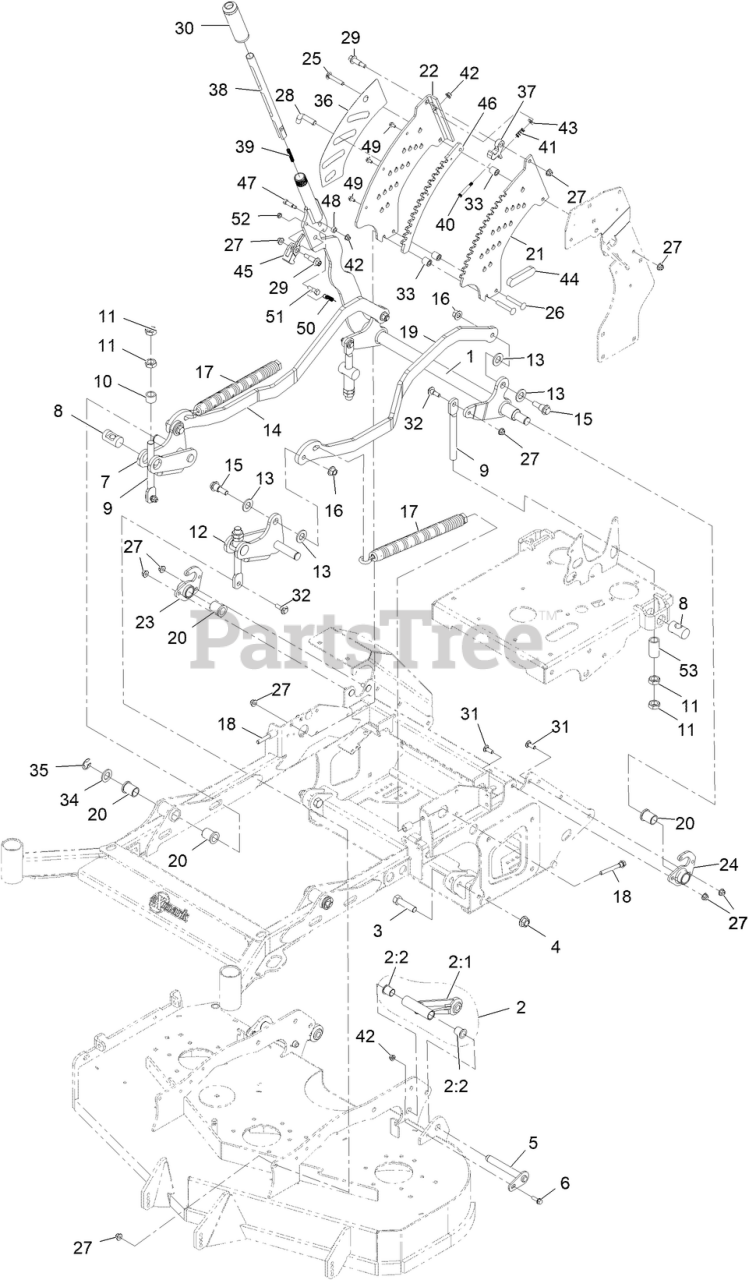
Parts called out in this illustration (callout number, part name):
1	CROSS SHAFT-DECKLIFT-REAR [BLACK]
2	ASM-DECK STRUT W/BUSHINGS
2:1	ASM-Deck Strut
2:2	BUSHING-IGUS FLNG .75X1
3	SCREW-HH
4	NUT-FLNG 5/8-18 CTRLOCK GR G
5	ASM-DECK STRUT PIN
6	SCREW-HHF
7	Weld-Arm-Decklift-Front-RH
8	TRUNION-DECK LIFT
9	Link,Deck Lift Adjuster
10	SPACER-DECKLIFT
11	NUT-JAM
12	Weld-Arm-Decklift-Front-LH
13	WASHER-FLAT
14	LINK-DECKLIFT-RH
15	SCREW-SHOULDER, HHF 1/2-13 X 1.12
16	Nut-Lock 1/2-13
17	SPRING-EXTENSION
18	BOLT-SHOULDER
19	LINK-DECKLIFT-LH
20	BUSHING-FLANGED
21	Plate-Inner-HOC
22	Plate-Outer-HOC
23	SUPPORT-HOC SHAFT RH
24	SUPPORT-HOC SHAFT LH
25	BOLT-CARR, SHORT NECK
26	SCREW-CARR
27	NUT-HF, NI
28	PIN-HOC
29	BOLT-SHOULDER
30	GRIP-HANDLE-DECKLIFT
31	SCREW-CARR
32	SCREW-SHOULDER, HHF
33	SPACER-HOC
35	RING-RETAINING, EXT
36	DECAL-HEIGHT OF CUT
37	PAWL-DECKLIFT
38	PLUNGER-TOP
39	SPRING-COMPRESSION
40	SCREW-SHOULDER-CAP
41	SPRING-COMPRESSION
42	NUT-HF, NI
44	PLATE-GUIDE HOC INNER
45	Pawl-Lock-Decklift
46	Plate-Doubler-HOC-Lock
47	BOLT-SHOULDER
49	SCREW-HWH
50	SPRING-EXTENSION
51	BOLT-SHOULDER
52	NUT-LOCK, NI
53	SPACER 1.13 O.D. X .81 I.D. X 2.05L
